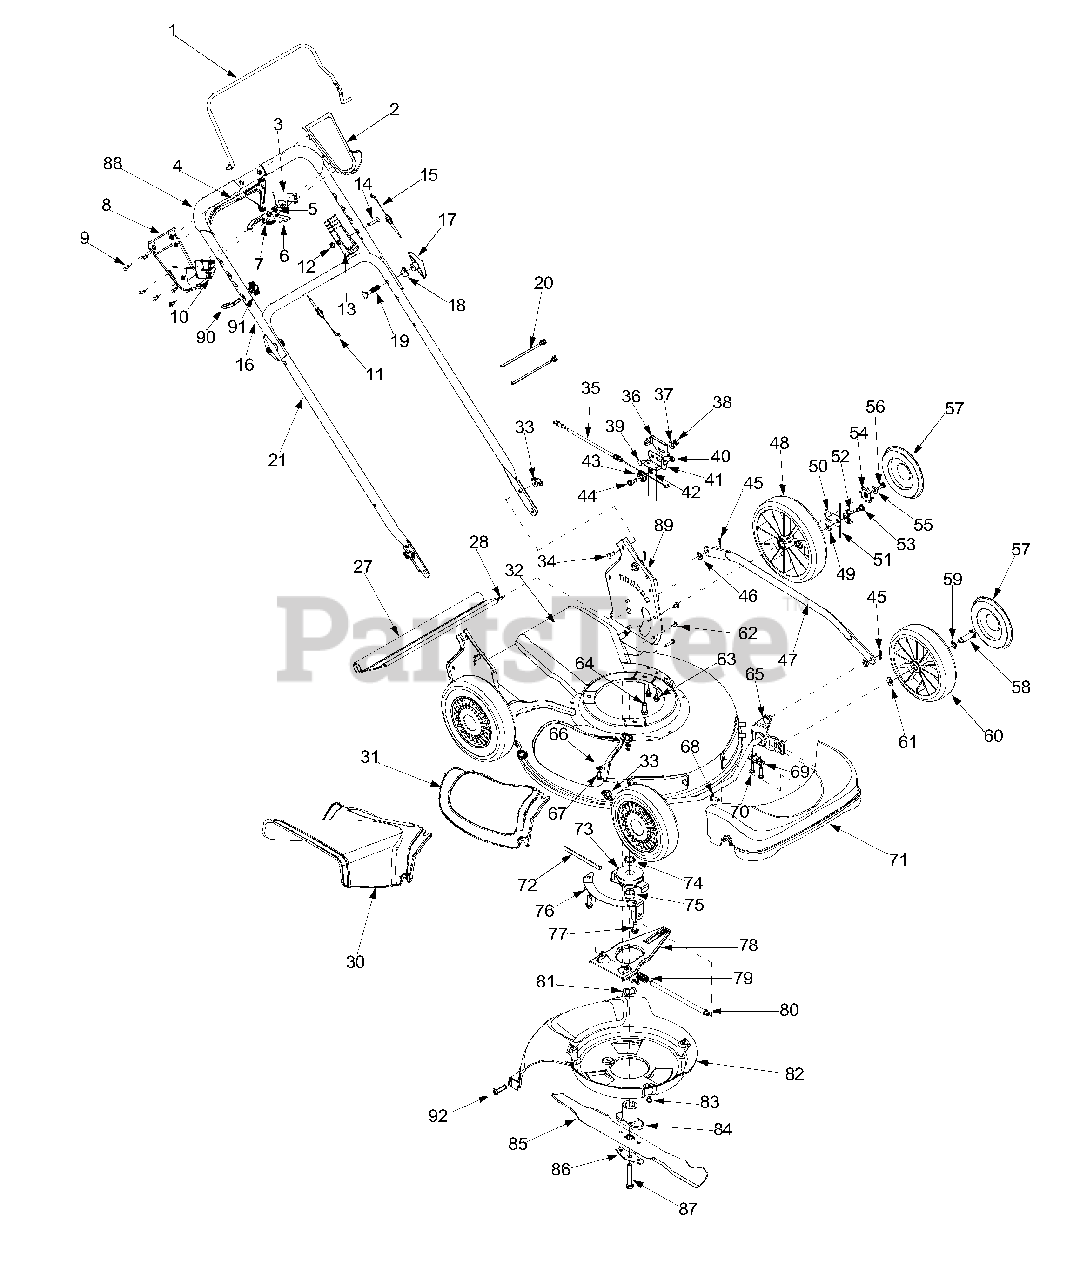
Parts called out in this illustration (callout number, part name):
1	Control Handle
2	Upper Control Handle
3	3 Spd. Rack Cable Bracket
4	Control Lever
5	Gear Insert
6	Shift Lever Spring
7	3 Speed Shift Lever
8	Lower Control Housing
9	C Sunk Tap Screw #10 x .75 Lg
10	Cable Mounting Cap
11	Drive Cable 51.0
12	Top Lock Nut 1/4-20
13	Control Housing
14	Oval C-Sunk Screw
15	Control Cable 46"
17	Wing Nut
18	Saddle Washer .320 ID x .830 OD
19	Carriage Bolt 5/16-18 x 2.0
20	Cable Tie
27	Trail Shield
28	Trail Shield Wire
30	Side Discharge Chute
31	Mulch Cover
34	Carriage Bolt 1/4-20 x .75
35	3 Speed Cable
38	Hex Nut 1/4-20
39	Carriage Screw 1/4-20 x .50
40	Hex Nut 1/4-28
43	Roller Cable
44	Shoulder Screw .375 ID x 1/4-14
45	Cotter Pin
46	Bowed Washer
48	Wheel 9 x 2
49	Top Lock Tab Weld Nut 1/4-20
50	Ratchet Pawl Plate
51	Plastic Spring Ratchet
53	Shld Screw .340 ID x .285 OD
54	Wheel Rachet
55	Bell Washer .265 ID x .75 OD
56	Hex Cap Screw 1/4-20 x .620
57	Hubcap
58	Shoulder Screw .498 x 1.445
59	Wave Washer .510 ID x .750 OD
60	Wheel 8 x 2
61	Spring Washer .401 ID x .870 OD
62	Screw 1/4-14 x .500
63	Screw 1/4-14 x .625
64	Hex Washer Screw 3/8-16 x 1.0
66	Flat Washer .344 ID x .62 OD
67	Carriage Screw 1/4-20 x .75
68	Torx Screw
69	Block Bushing
70	Hex Washer Screw
71	Front Axle Cover
72	Belt 3/8 x 39.24
73	Pulley Assembly
74	Sleeve Spacer .88 ID x 1.13 OD
75	Sleeve Spacer .88 ID x 1.00 OD
77	Screw 3/8-18 x 1.0
80	Pivot Shaft
81	Wave Washer 1.38 ID x .88 OD
82	Baffle
83	Screw 1/4-20 x 3.75
84	Blade Adapter Kit
85	21" Mulching Blade
86	Blade Bell Support
87	Hex Bolt 3/8-24 x 2.5
88	Grip
92	Hi-Low Scr. #12
